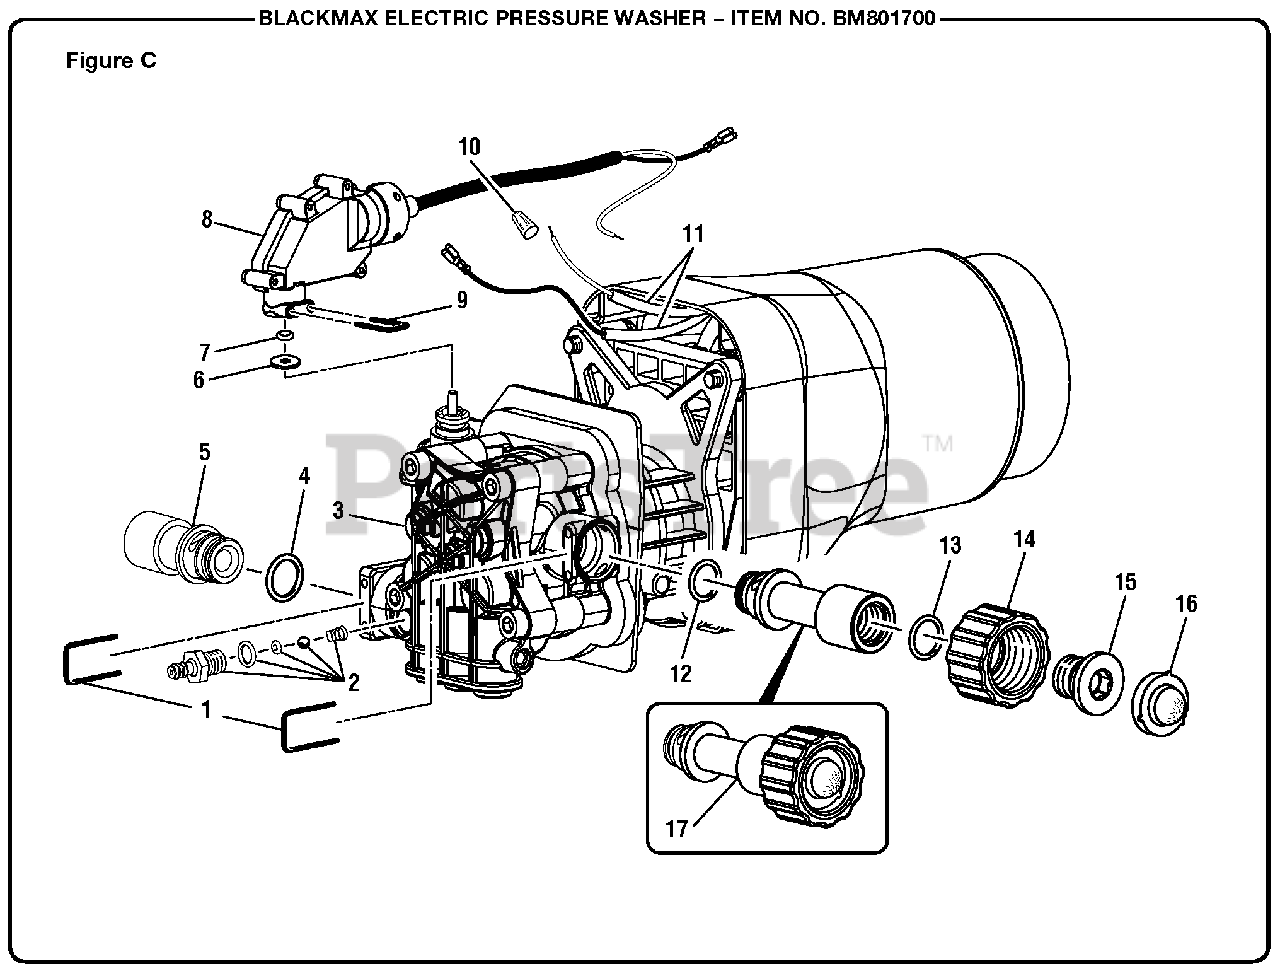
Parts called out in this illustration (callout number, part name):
2	Detergent Nipple Assembly
3	Motor and Pump Assembly
5	Outlet Tube Assembly
6	Washer (Brass)
7	O-Ring
8	Pressure Switch
14	Water Inlet Connector
15	Water Inlet Screw Nut
16	Water Inlet Filter
17	Inlet Tube Assembly
